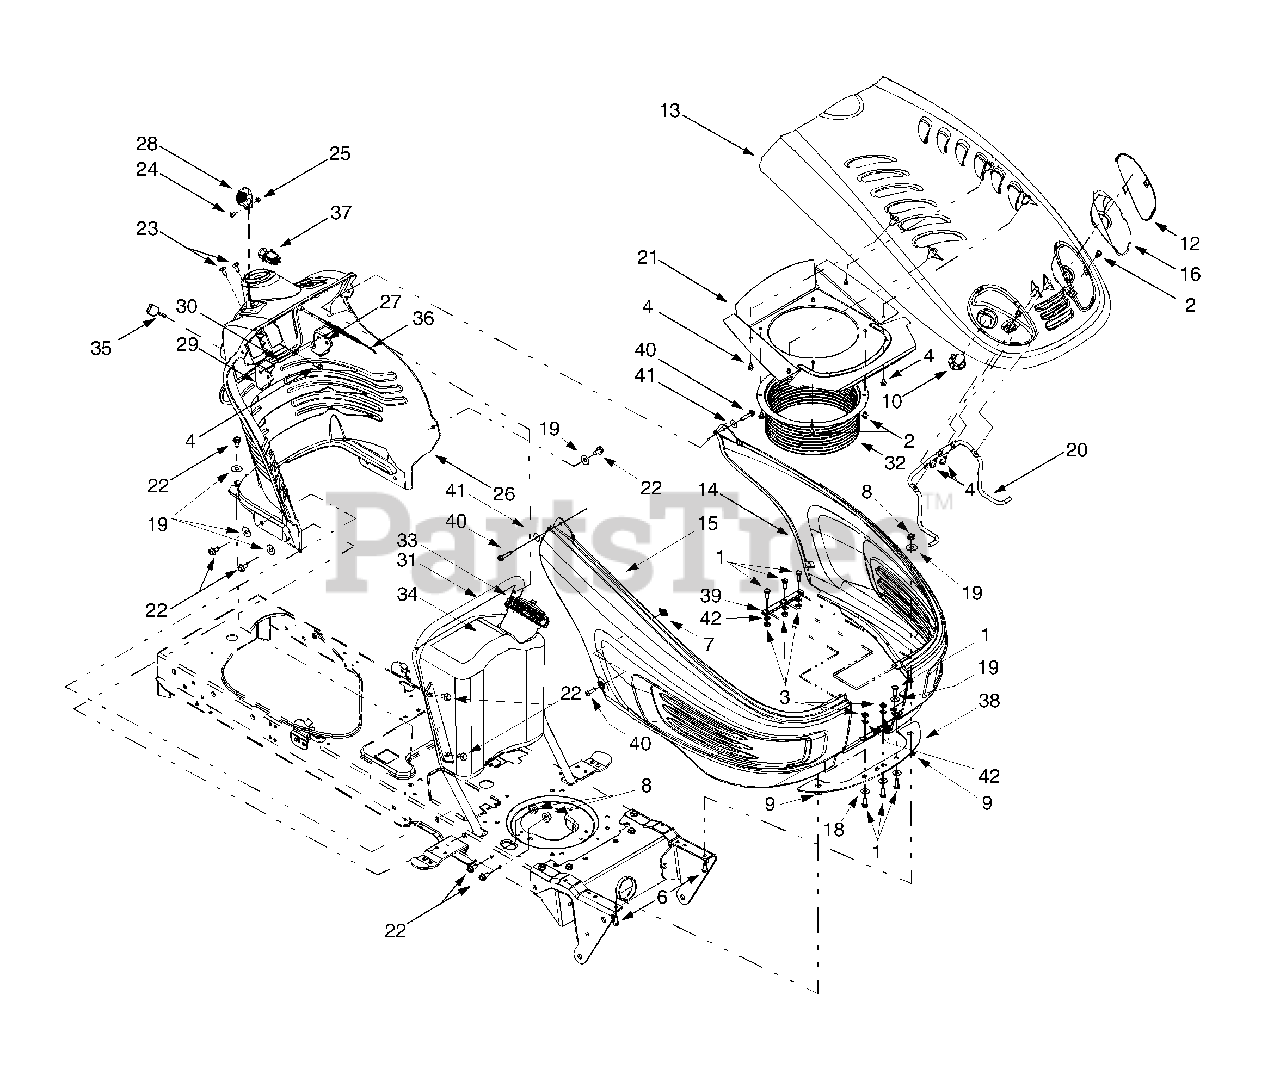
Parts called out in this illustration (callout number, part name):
1	Hex Cap Screw, 1/4-20 x .75
2	Self-tapping Screw, 1/4-20 x .5
3	Hex Nut, 1/4-20
4	Self-tapping Screw, 1/4-15 x .75
6	Hex Cap Screw, 5/16-18 x 1.25
7	U-type Speed Nut, 1/4-20
8	Flange Lock Nut, 5/16-18
9	Speed Nut
10	Head Lamp Socket
12	LH Head Light Lens
13	Hood, 4-style (Yellow)
14	LH Side Panel, 4-style (Yellow)
15	RH Side Panel, 4-style (Yellow)
16	LH Head Light Reflector
18	Flat Washer, .28 x .74 x .063
19	Flat Washer, .349 x 1.0 x .063
20	Hood Support Rod
22	Self-tapping Screw, 5/16-18 x .625
23	Torx Self-tapping Screw, 1/4-14 x .625
24	Torx Screw, #8-32 x .375
25	Hex Nut, 8-32
26	Dash Panel, 4-style
27	Parking Brake Button
28	Throttle Control Lever
29	Cruise Control Button
30	Brake/Cruise Pivot Rod
33	Fuel Cap
34	Fuel Tank (three gallon)
35	Ignition Key w/ plastic cover
36	Choke Cable
37	Electric PTO Switch
38	Heat Shield
41	Flat Washer, .283 x .75 x .030
42	Lock Washer, 1/4
